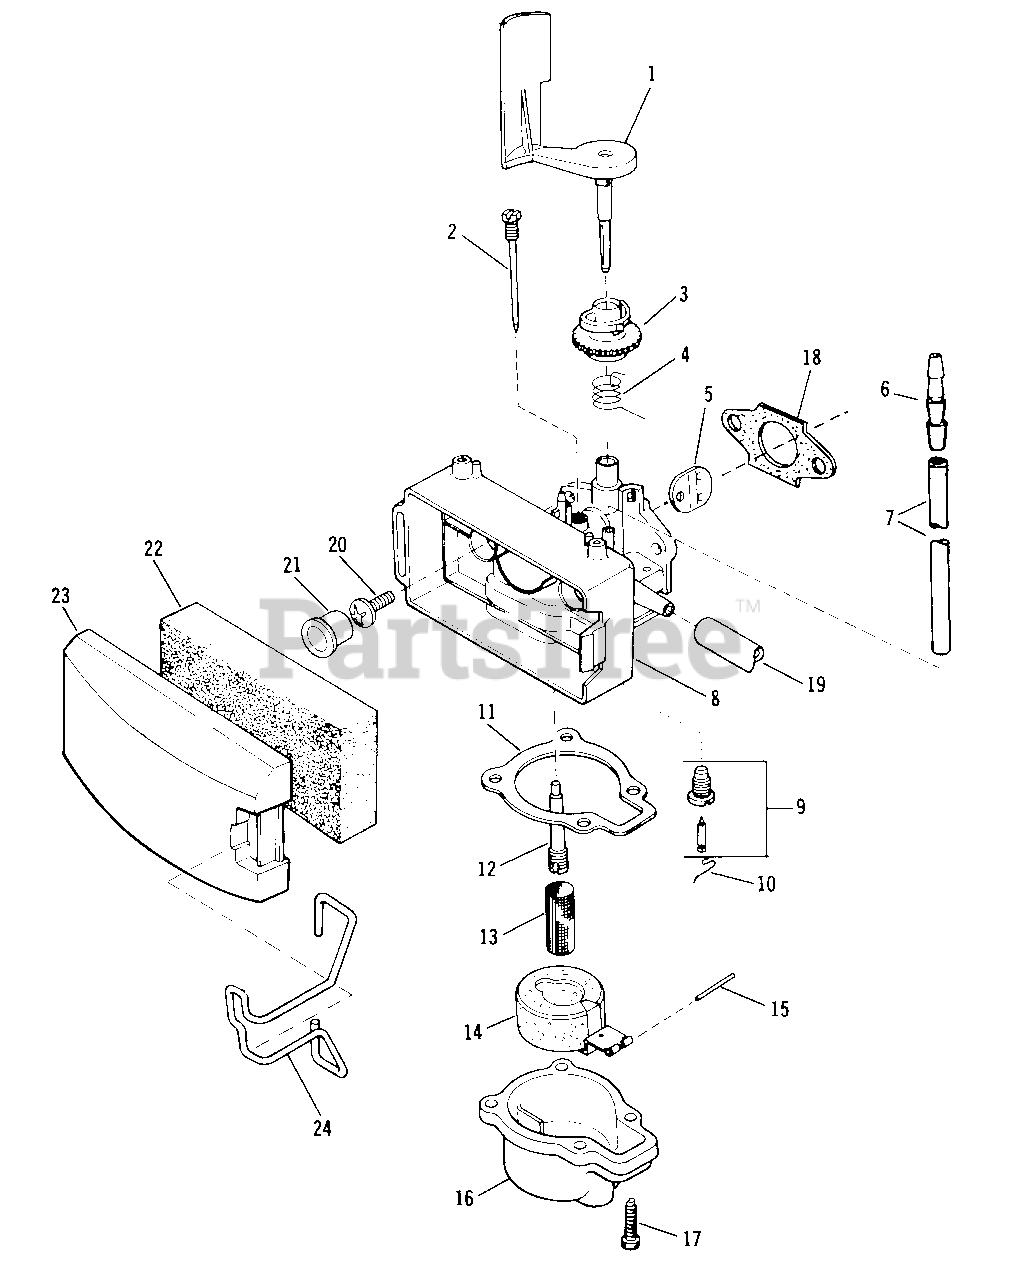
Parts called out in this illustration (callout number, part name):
1	Air Vane and Shaft
2	Needle Adj. Assembly
5	Disc-Throttle
6	Connector-Reducer
7	Tube-Primer
8	Carburetor Body
9	Float Valve and Seat Assembly
10	Clip
11	Gasket
12	Nozzle
13	Filter-Carburetor
14	Float and Arm Assembly
15	Pin-Float
16	Float Chamber
17	Screw-Float Chamber
18	Gasket-Carb. to Crankcase Cover
19	Fuel Line
20	Screw-Carb. Mounting
21	Plug
22	Element-Air Filter
23	Cover-Air Filter
24	Retainer-Filter Cover
